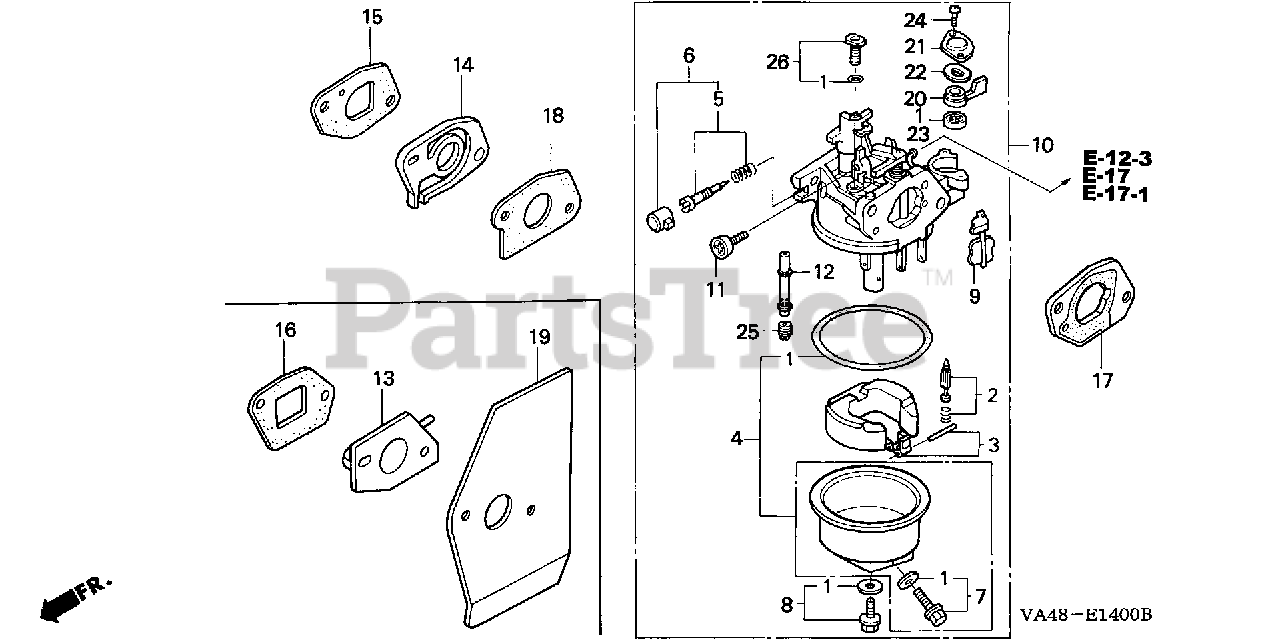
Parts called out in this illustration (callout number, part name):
1	GASKET SET (CARBURETOR NO.)
2	VALVE SET, FLOAT (CARBURETOR NO.) (SEAT NOT INCLUDED)
3	FLOAT SET
4	CHAMBER SET, FLOAT (CARBURETOR NO.)
5	SCREW SET, PILOT (Honda Code 1441500). (CARBURETOR NO.)
7	SCREW SET, DRAIN (Honda Code 1672187). (CARBURETOR NO.)
8	SCREW SET B
8	SCREW SET
9	CHOKE SET (CARBURETOR NO.)
10	CARBURETOR ASSY. (BE46B A)
11	SCREW, THROTTLE STOP
12	NOZZLE, MAIN
14	INSULATOR, CARBURETOR
15	GASKET, CARBURETOR (HPE)
17	SPACER, CARBURETOR
18	GASKET, CARBURETOR
20	LEVER, PETCOCK (CARBURETOR NO.)
21	PLATE, LEVER SETTING (CARBURETOR NO.)
22	SPRING, PETCOCK LEVER (CARBURETOR NO.)
23	GASKET, VALVE
24	SCREW, PAN (3X6)
24	SCREW, PAN (3X8) (CARBURETOR NO.)
25	JET, MAIN (#62)
25	JET, MAIN (#58) Use from Engine SN BE30B E.
25	JET, MAIN (#60)
26	JET SET, PILOT (#35)
